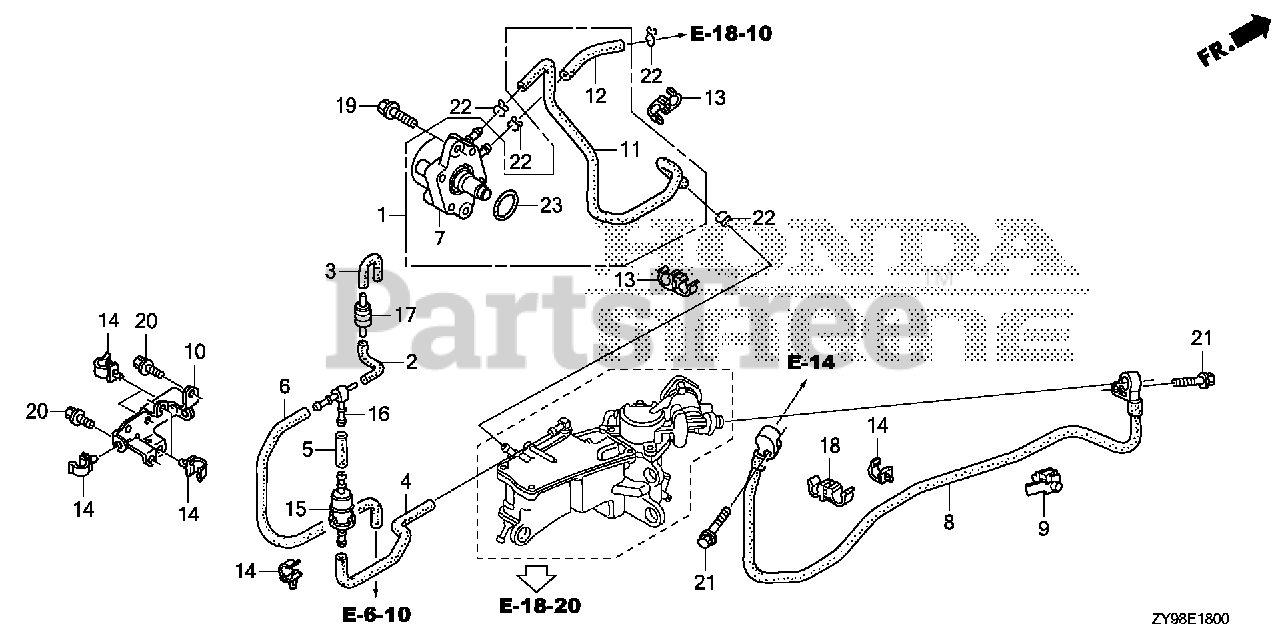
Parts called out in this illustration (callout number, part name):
1	PUMP ASSY. KIT, FUEL (MSDS)
2	TUBE A, CHECK VALVE
3	TUBE B, CHECK VALVE
4	TUBE A, AIR VENT
5	TUBE B, AIR VENT
6	TUBE C, AIR VENT
7	PUMP ASSY., FUEL (MSDS)
8	HOSE, FUEL
9	GROMMET, FUEL HOSE
10	BRACKET, FUEL TUBE CLAMP
11	TUBE D, FUEL
12	TUBE E, FUEL
13	CLAMP A, FUEL TUBE
14	CLAMP B, FUEL TUBE
15	FILTER, FUEL
17	VALVE, CHECK
18	CLAMP, OXYGEN SENSOR
19	BOLT, FLANGE (6X22)
20	BOLT, FLANGE (6X14) (CT200)
21	BOLT, FLANGE (6X25)
22	CLIP, TUBE (B12)
23	O-RING (31.2X2.4)
